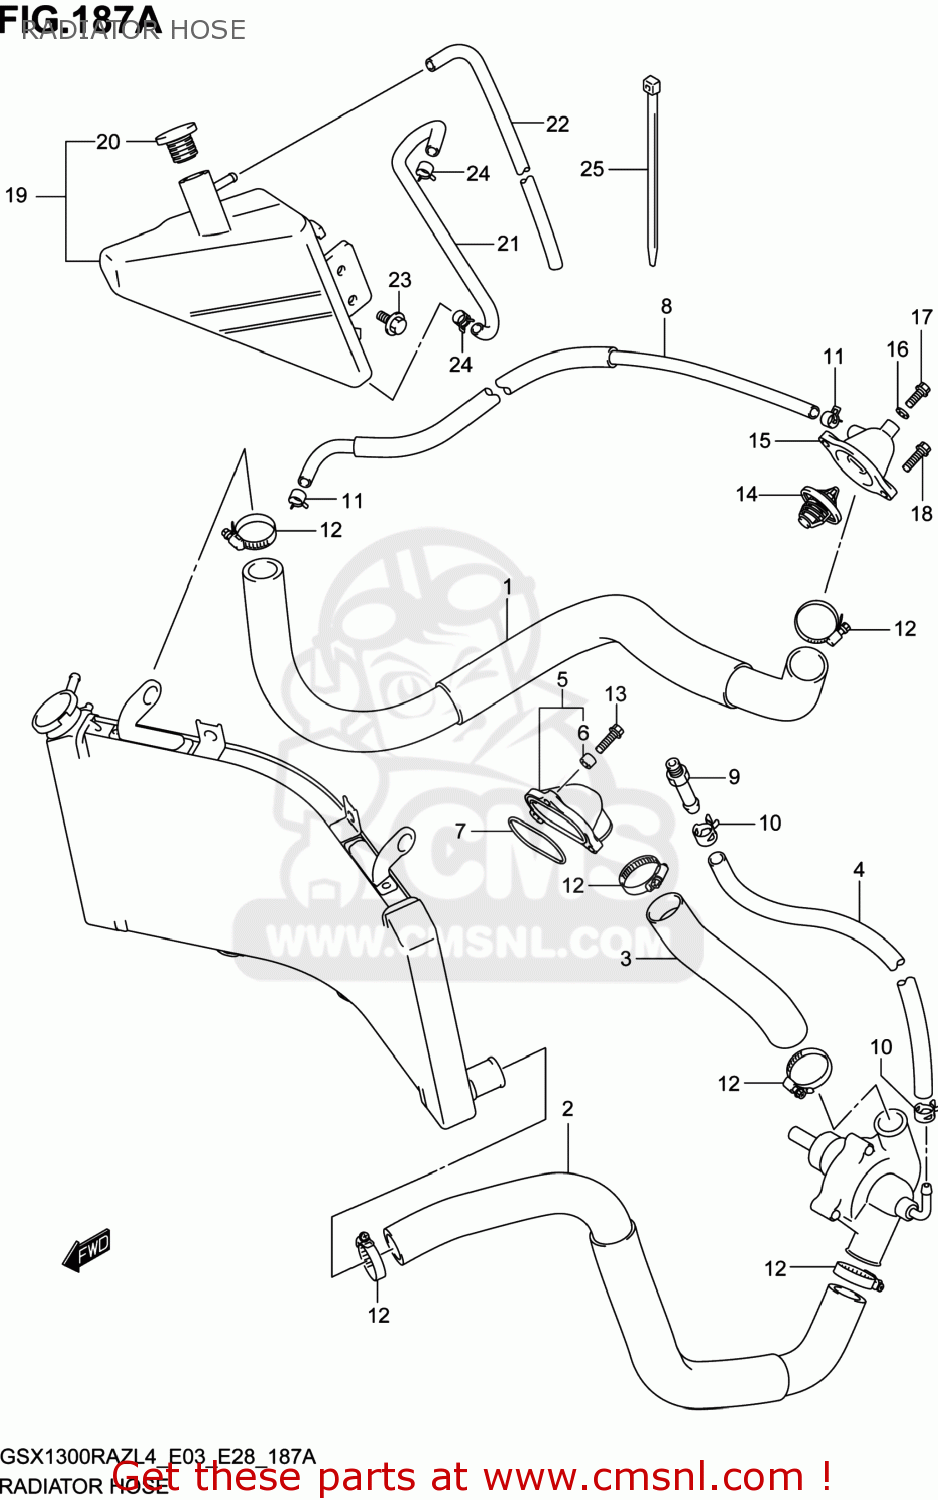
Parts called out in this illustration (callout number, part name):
1	HOSE,RADIATOR INLET
2	HOSE,RADIATOR OUTLET
3	HOSE,CYLINDERL INLET
4	HOSE,WATER BYPASS NO.1
5	CONNECTOR,CYLINDER WATER INLET
6	SPACER(6.5X9X8)
7	O RING,CYL WATER CONNECTOR
8	HOSE,WATER AIR BLEED
9	BOLT UNION
10	CLAMP
11	CLIP
12	CLAMP
13	BOLT
14	THERMOSTAT,WATER
15	COVER,THERMOSTAT
16	GASKET(6.4X11.5X0.8) (NAS)
17	UNION BOLT,AIR VENT
18	BOLT
19	TANK ASSY,RESERVOIR
20	CAP,RESERVOIR TANK
21	HOSE,RESERVOIR TANK INLET
22	HOSE,RESERVOIR TANK OVFL
23	BOLT(6X12)
24	CLIP
25	CLAMP(L:145)
